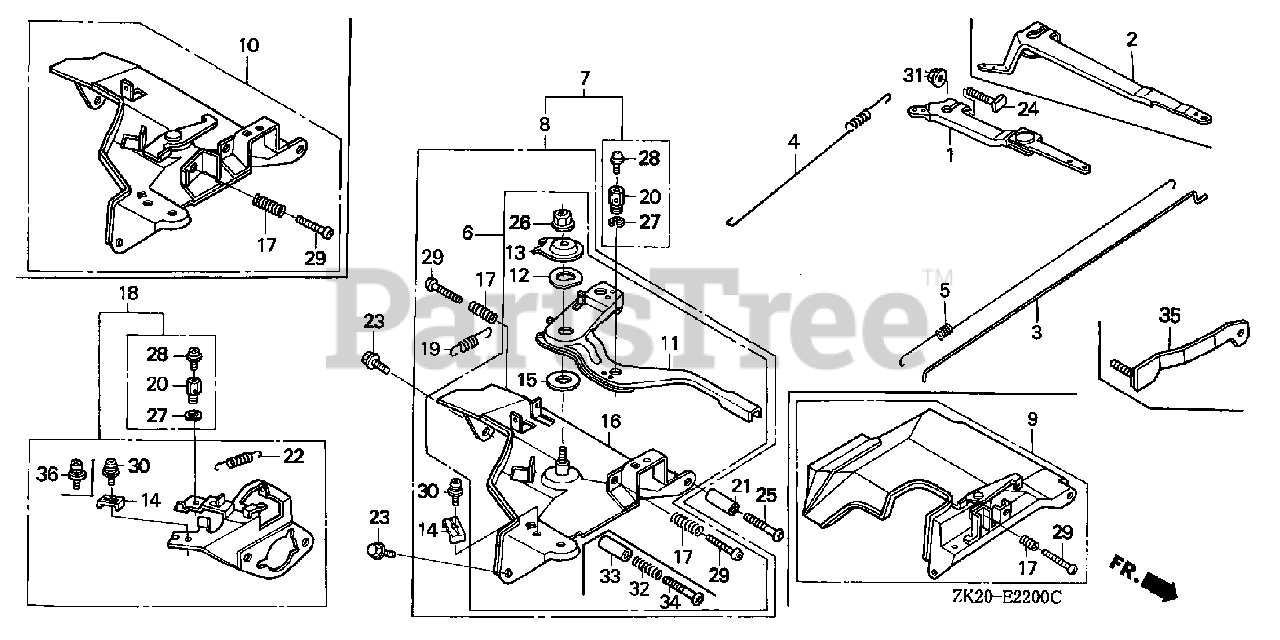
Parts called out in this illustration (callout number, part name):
2	ARM, GOVERNOR
3	ROD, GOVERNOR
4	SPRING, GOVERNOR
5	SPRING, THROTTLE RETURN
8	CONTROL ASSY. (REMOTE)
11	LEVER, CONTROL
12	SPRING, LEVER
13	WASHER, CONTROL LEVER
14	HOLDER, CABLE
15	SPACER, CONTROL LEVER
16	BASE, CONTROL
17	SPRING, CONTROL ADJUSTING
19	SPRING, CABLE RETURN
23	BOLT, FLANGE (6X12) (CT200)
24	BOLT, GOVERNOR ARM
26	NUT, SELF-LOCK (6MM)
29	SCREW, PAN (5X28)
30	SCREW, PAN (5X16)
31	NUT, FLANGE (6MM)
